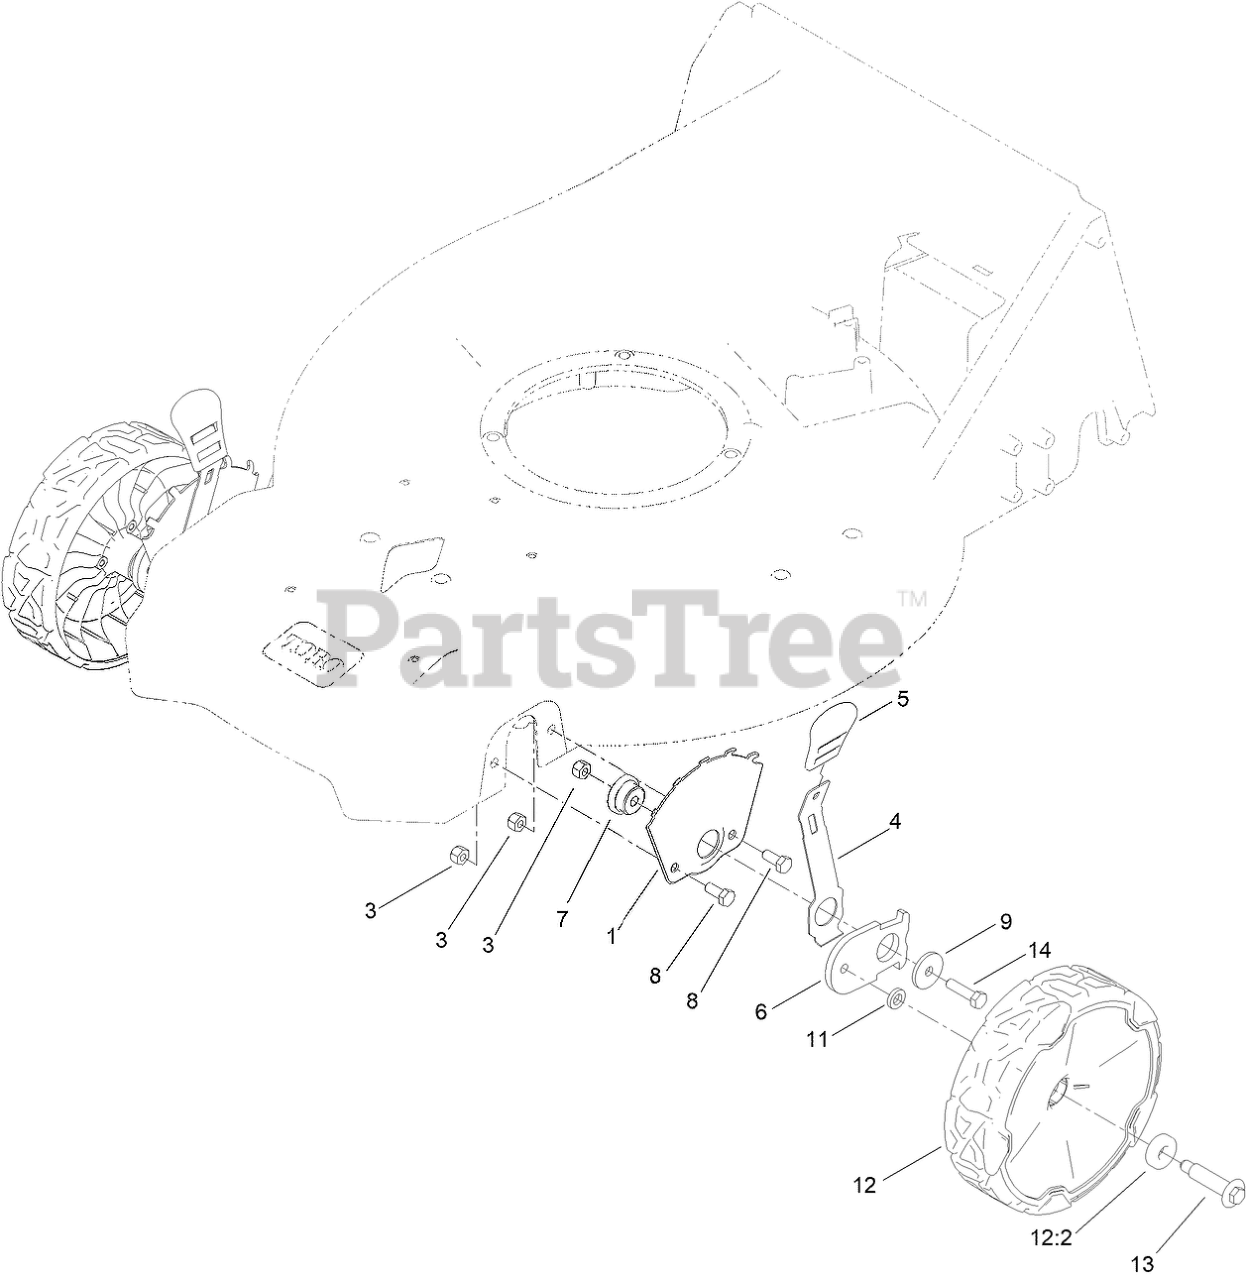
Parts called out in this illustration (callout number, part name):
1	PLATE-HOC,FRONT FSVQ WEDNESDAY
3	NUT-HEX
4	ARM-SPRING
5	KNOB-HOC
6	ARM-PIVOT, FRONT
7	BUSHING-MOUNT, HOC
8	SCREW-HH
9	WASHER-FLAT
11	WASHER-WHEEL BOLT
12	ASM-WHEEL, 8" (BEARINGS)
12:2	BEARING-WHEEL
13	WHEEL BOLT
14	SCREW-HH
